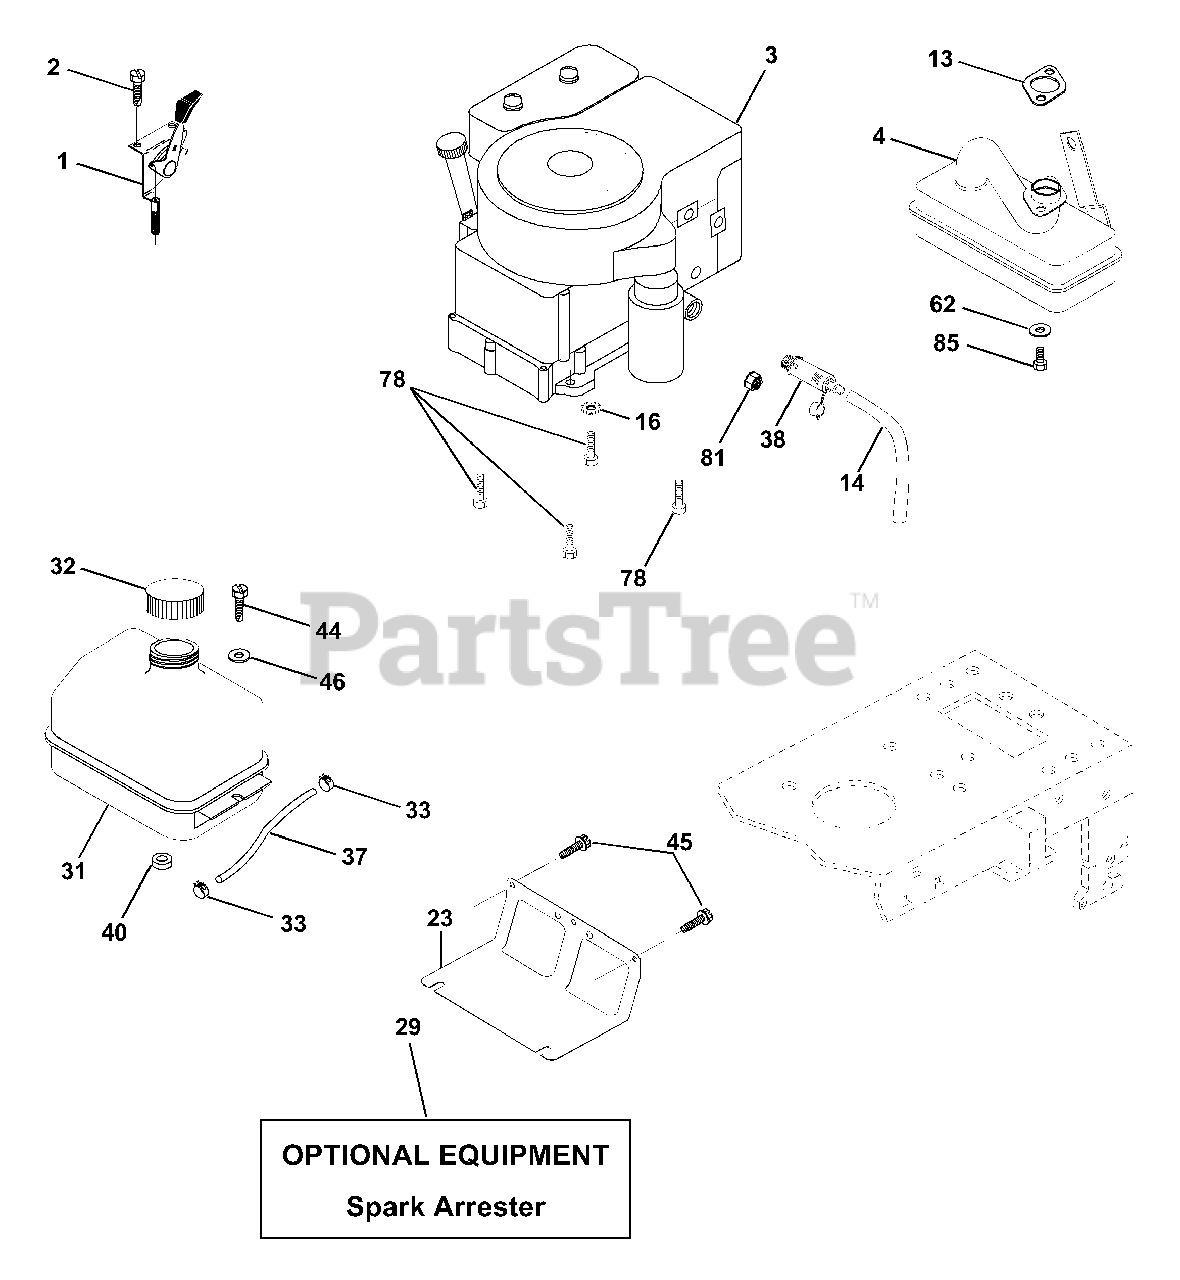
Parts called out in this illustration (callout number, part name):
1	Control Th/ch Flag
2	Screw Hex Thd Cut 1/4-20x5/8 T
4	Muffler Exhaust
13	Gasket Eng 1 313 Id Tin Plated
14	Tube Drain Oil Easy
16	Washer Lock Ext Tooth 3/8
23	Shield BRN/DBR Guard
29	Kit Spark Arrestor (Flat Scrn)
31	Tank Fuel Front
32	Cap Asm Fuel
33	Clamp Hose
37	Line Fuel 20"
38	Plug Drain Oil Easy
40	Bushing Snap Nyl Blk Fuel Line
44	Screw Thdrol 1/4-20 x 3/4
45	Screw Hex Wsh Thdrol 3/8-16
46	Washer 9/32 X 7/8 X 16 Ga
62	Washer Lock Hvy Hlcl Spr
78	Screw 3/8-16 x 1-1/4
81	Nut Keps Hex 1/4-20 Unc
85	Bolt Hex HD. Phillips
